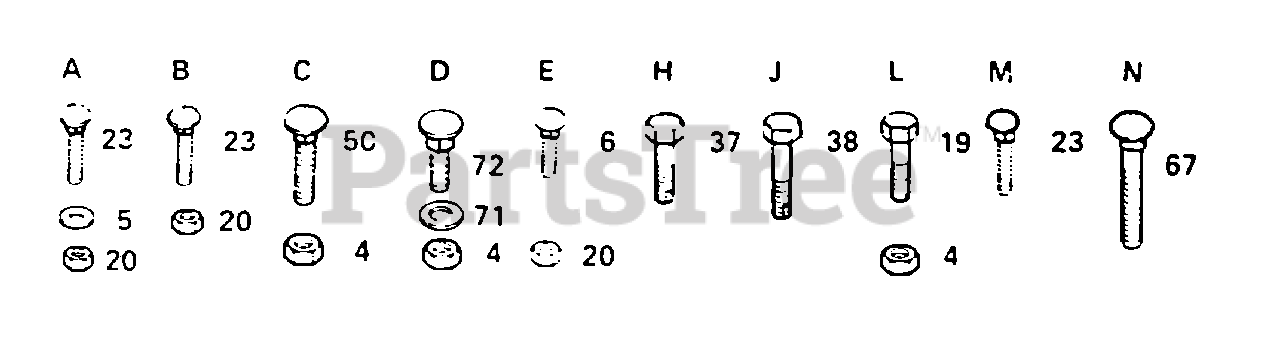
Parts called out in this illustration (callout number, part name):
5	WASHER M
6	BOLT
23	BOLT
37	SCREW
38	SCREW
50	BOLT
67	BOLT.3/8-14X1.25
71	WASHER
72	BOLT
